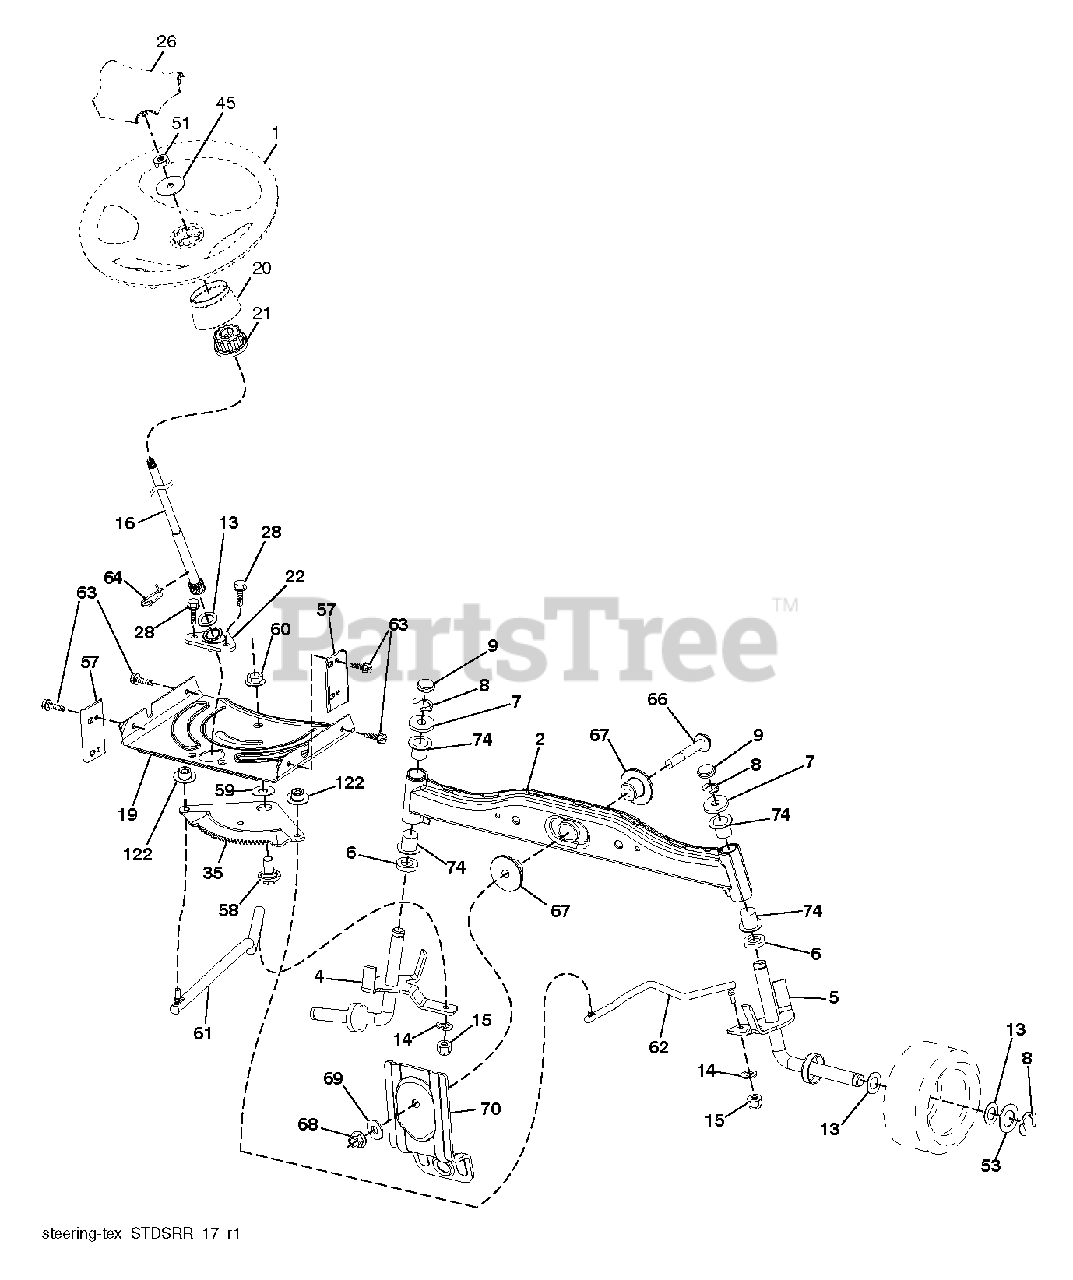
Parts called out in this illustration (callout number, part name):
1	WHEEL.STEERING.STDSRR.BLK/OV
2	AXLE HALF ASM-WELDED
4	SPINDLE.WELDED.LH.15"TEX
5	SPINDLE.WELDED.RH.15"T
8	RING CLIP
9	CAP.SPINDLE
14	WASHER, LOCK 3/8
15	NUT CROWNLOCK 3/8-24
16	SHAFT.STEER.STEALTH.DD
19	PLATE.STEER.DDL.NLT/NG
21	ADAPTER, WHEEL STNG..
22	STEERING.SUPT.LOWER.
26	CAP.WHL.STRNG.STDSRRD.SRS.BLK
28	SCREW, 3/8-16X3/4
35	GEAR.SECTOR.PLATE.DDL.
45	WASHER 9/16"ID, 2 3/8"OD
51	NUT.HEX.1/2-20
53	WASHER.HARDENED
57	BRACKET.UPSTOP.TEX
58	BOLT.SHOULDER.SECTOR.P
59	WASHER.THURST.SECTOR.S
60	NUT FLANGE LOCK 5/8-11
61	DRAGLINK.LH.BALLSTUD.D
62	DRAGLINK.RH.BALLSTUD.D
63	SCREW
64	RETAINER.CLIP.SPRING.S
66	BOLT HEX FGHD 7/16-14 X 3 SERR
67	BUSHING.PM.FRONT AXLE
68	NUT.LOCK.FLANGE.7/16
69	WASHER.1.5X.505X.118
70	BRKT.DECK.SUSPENSION.F
74	BRNG T
